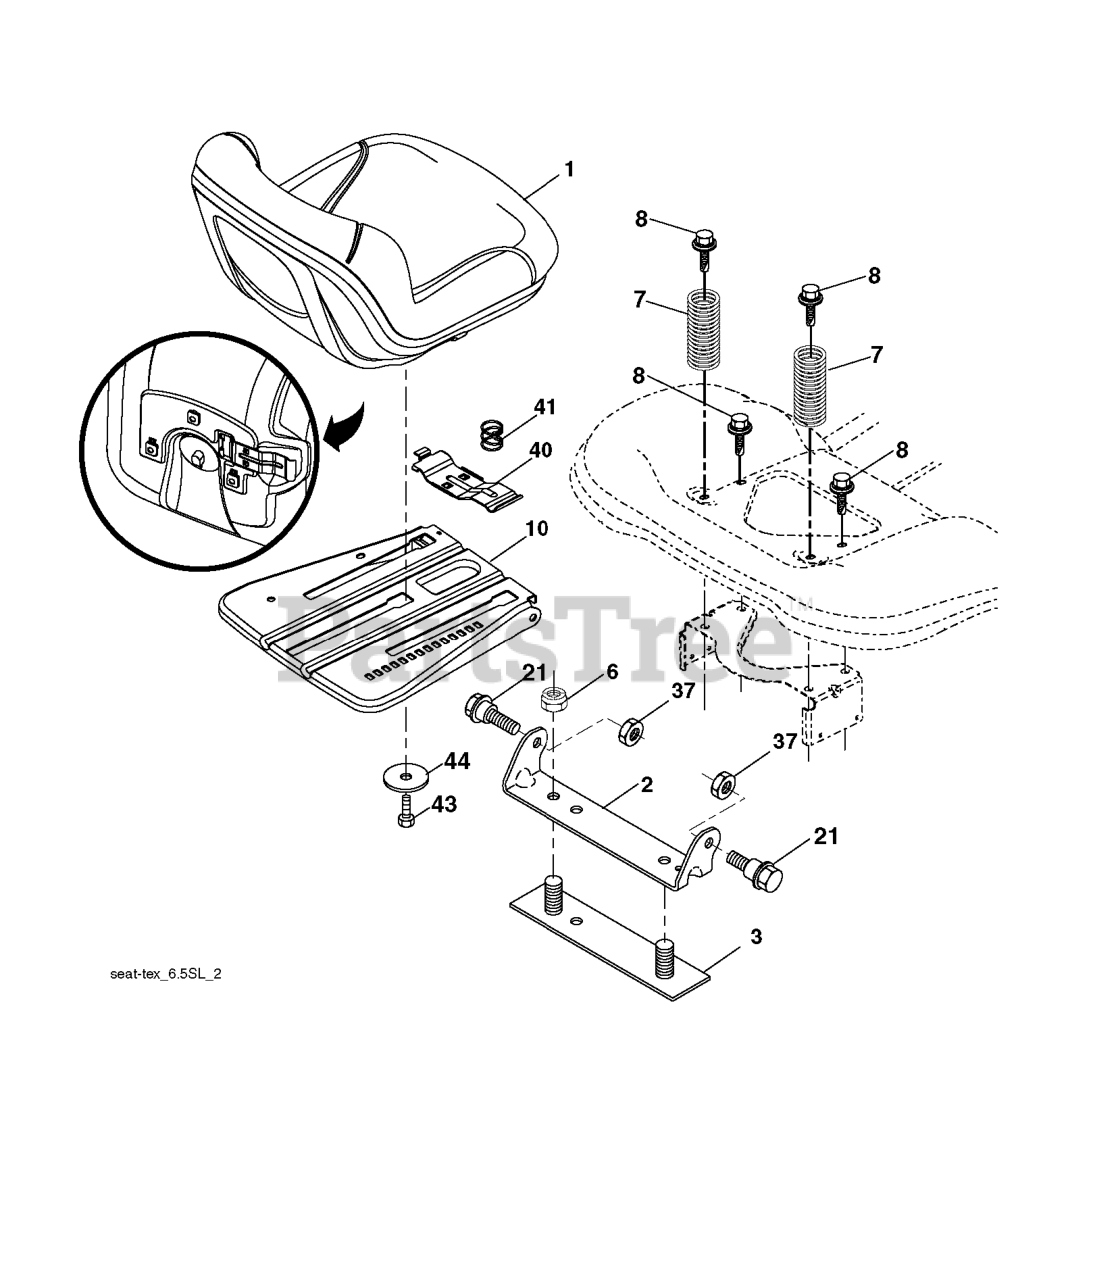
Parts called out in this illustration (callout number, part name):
1	RP SEAT.TH130.GRY.MILSCO.
2	BRKT.PIVOT.FENDER
3	STRAP
6	NUT
7	SPRING COMPRESSION
8	BOLT.5/16-18UNCX3/4 W/SEMS.BLK
10	PAN.ASM.SEAT.3PT
21	BOLT.SHOULDER.5/16-18
37	NUT.71038.31-18.HEX.NYLOCK
40	HANDLE.SLIDE.SEAT.TEX.BLACK
41	SPRING.LATCH.SEAT.TEX
44	WASHER 13/32 X 2-3/8 X 12GA
